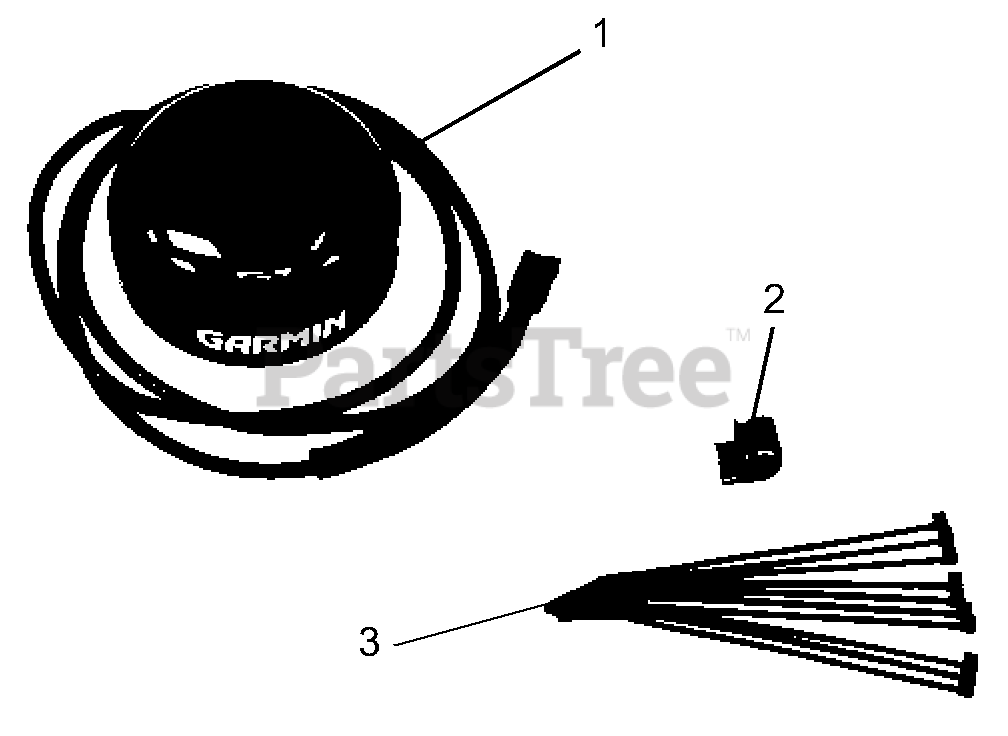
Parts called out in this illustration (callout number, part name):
1	HARNESS, GRAMIN GPS
2	J-CLAMP
3	CABLE TIE LG 5-1/2
